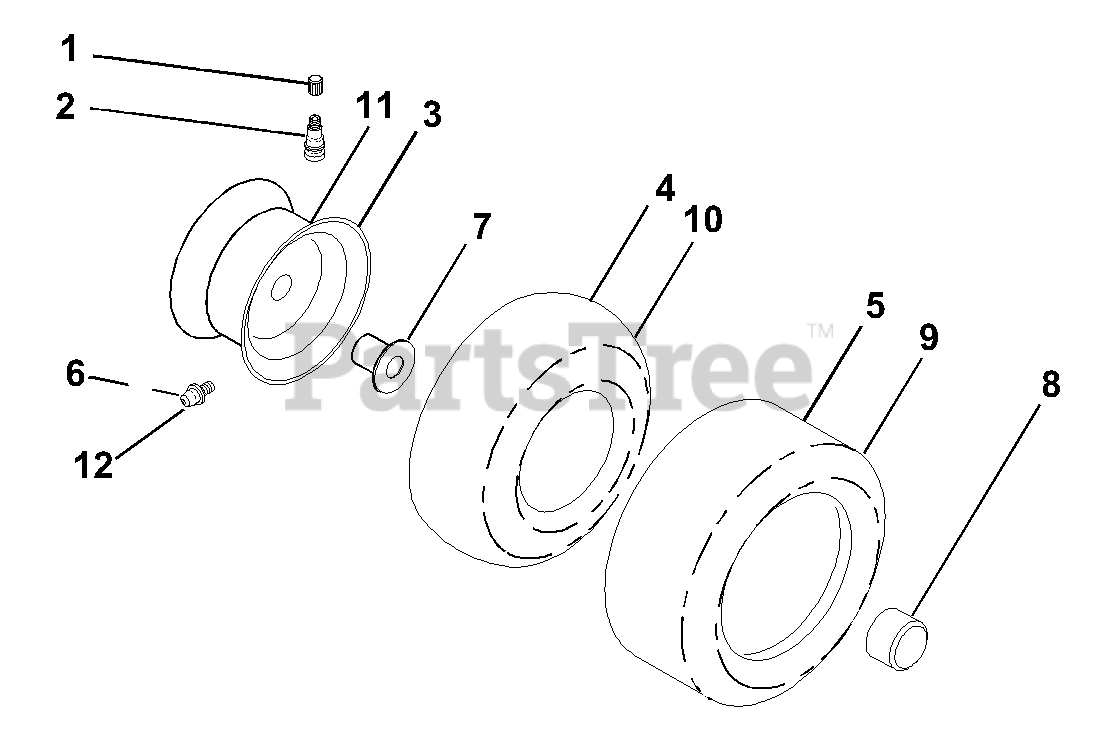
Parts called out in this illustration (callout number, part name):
1	Cap, Valve, Tire
2	Stem, Valve
3	Rim Assembly, Front
4	Tube, Front
5	Tire, Front
6	Fitting, Grease
7	Bearing, Flange
8	Cap, Hub
9	Tire, Rear
10	Tube, Rear
11	Rim Assembly, Rear
12	Fitting, Grease
